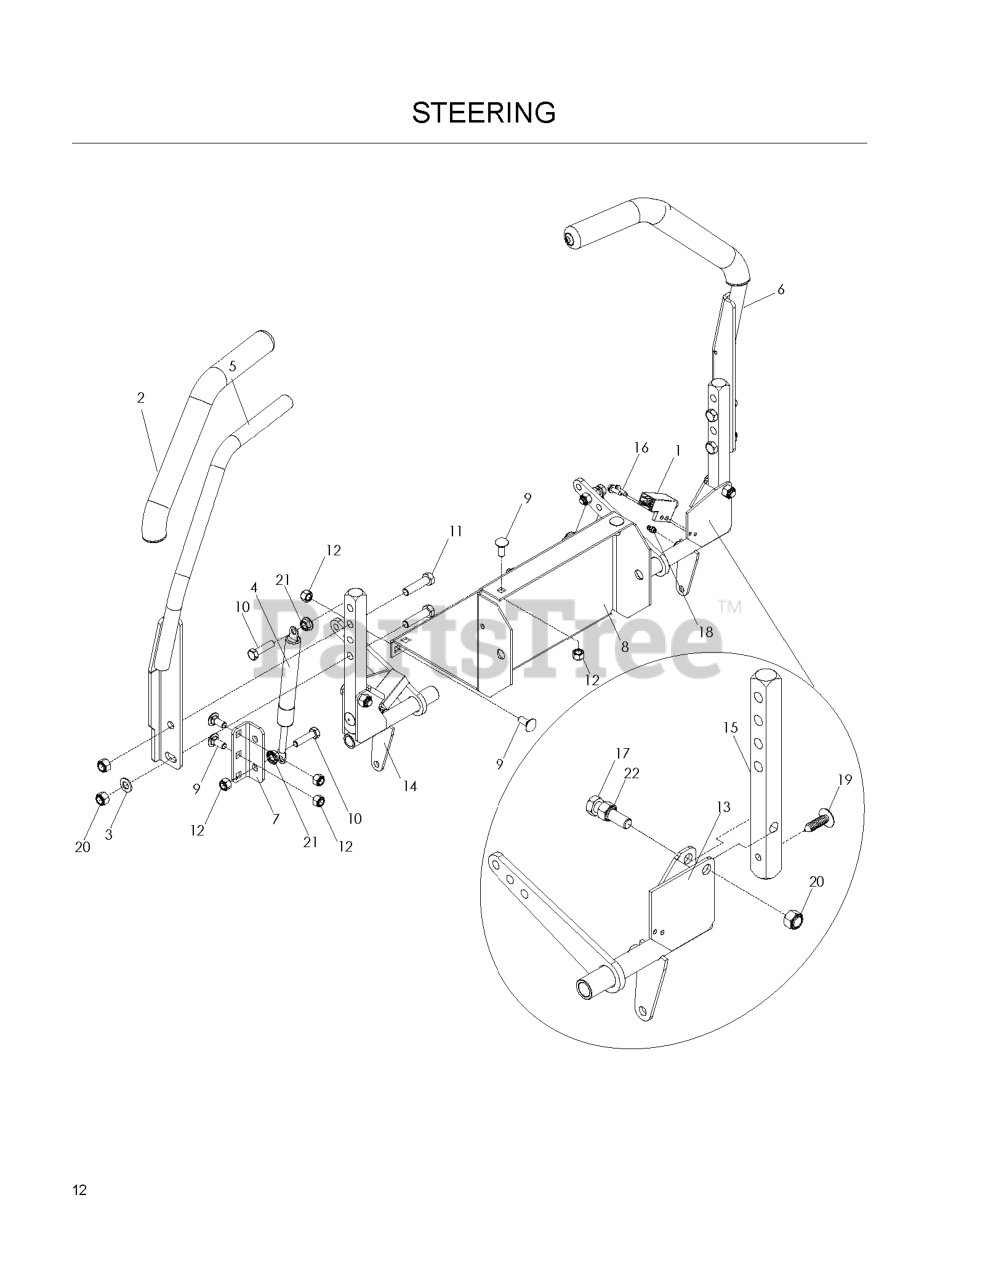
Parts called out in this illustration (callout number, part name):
1	SWITCH, INTERLOCK
3	WASHER, 3/8 DISC SPRING SPEC
5	RT DRIVE LEVER WLDMT
6	LT DRIVE LEVER WLDMT
7	DAMPENER BRACKET
8	BATTERY TRAY
9	BOLT 5/16C X 3/4" CARRIAGE
10	HCS 5/16C X 1 1/4
11	HCS 3/8C X 1 1/2
12	NUT 5/16 NYLOC
13	CONTROL WELDMENT, LEFT
14	CONTROL WELDMENT, RIGHT
15	CONTROL ARM
16	SCREW #10 X 1/2 SELF TAPPING
17	HCS 3/8-16 X 2-1/2 TPBLT
18	ZERK
19	RIVET, NYLON PUSH-IN
20	NUT 3/8-16 NYLOC
21	NUT 5/16C WHIZ
22	NUT 3/8C CENTERBLOCK
